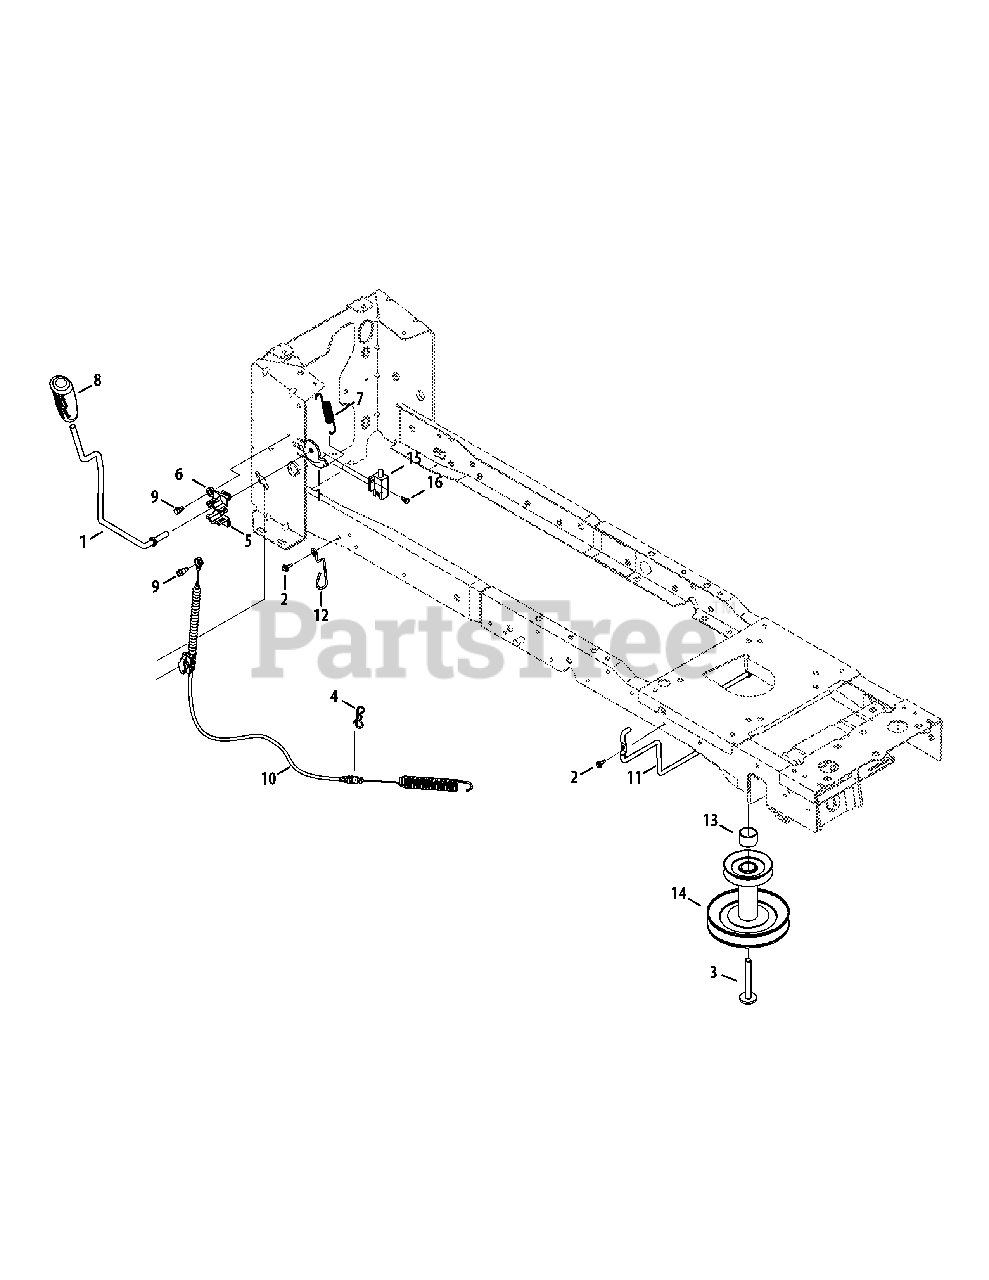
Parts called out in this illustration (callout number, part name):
1	PTO Handle Assembly
2	Screw, M6-1 x .625
3	Hex Cap Screw, 7/16-20 x 3.50
4	Bow-Tie Cotter Pin
5	PTO Handle Mount, RH
6	PTO Handle Mount, Top
7	Extension Spring, .56 OD x 4.52 LG
9	Shoulder Screw, .342 x .335, 1/4-28
10	PTO Cable
11	Engine Pulley Keeper Rod
12	Cable Guide
13	Spacer, Engine Pulley
14	Pulley, Engine, 3.56 x 6.12 Dia.
15	Switch, Interlock
16	Shoulder Screw, #10-32 x .500
